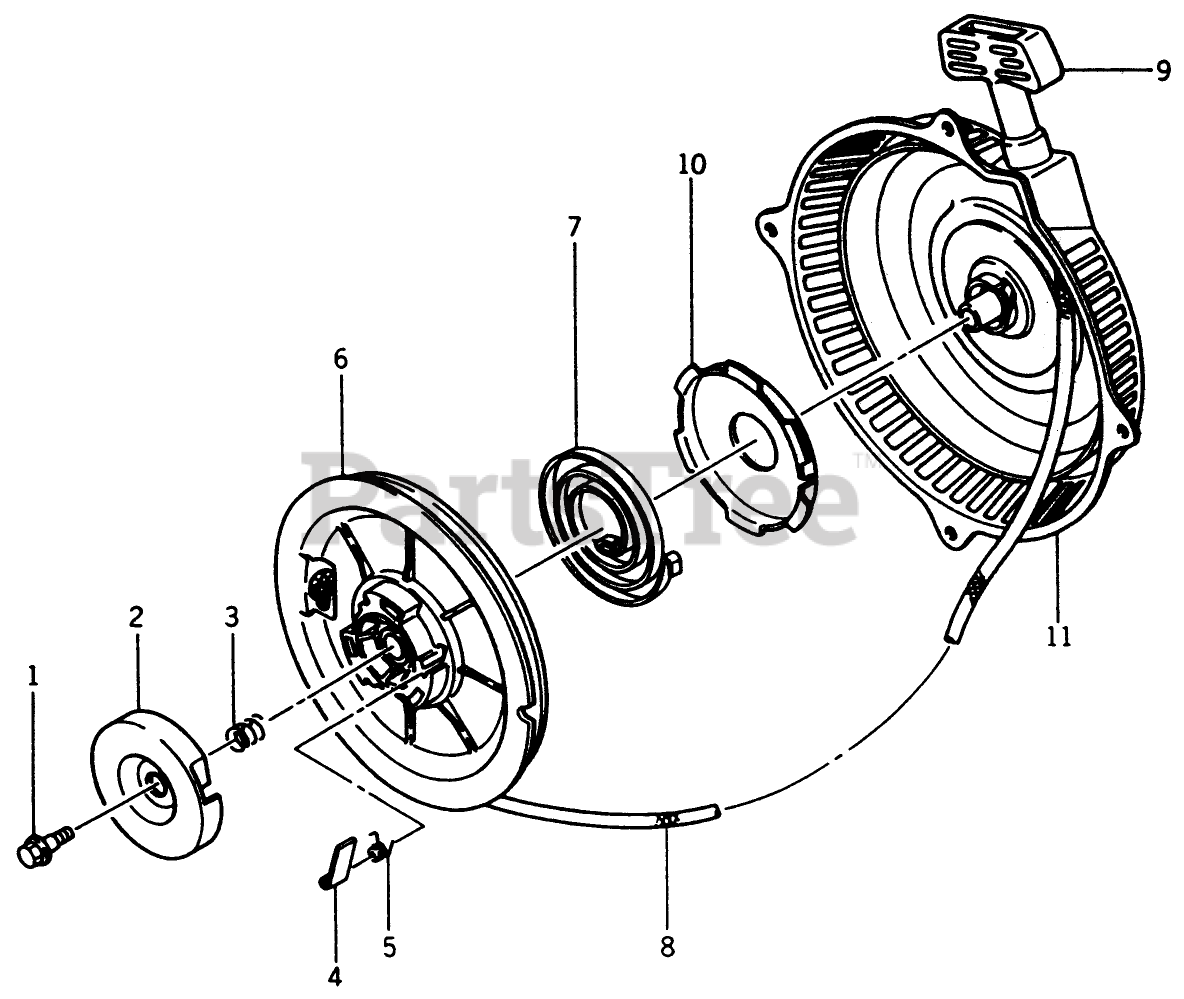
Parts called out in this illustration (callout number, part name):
2	Retainer
3	Return Spring
5	Spring-RETURN
